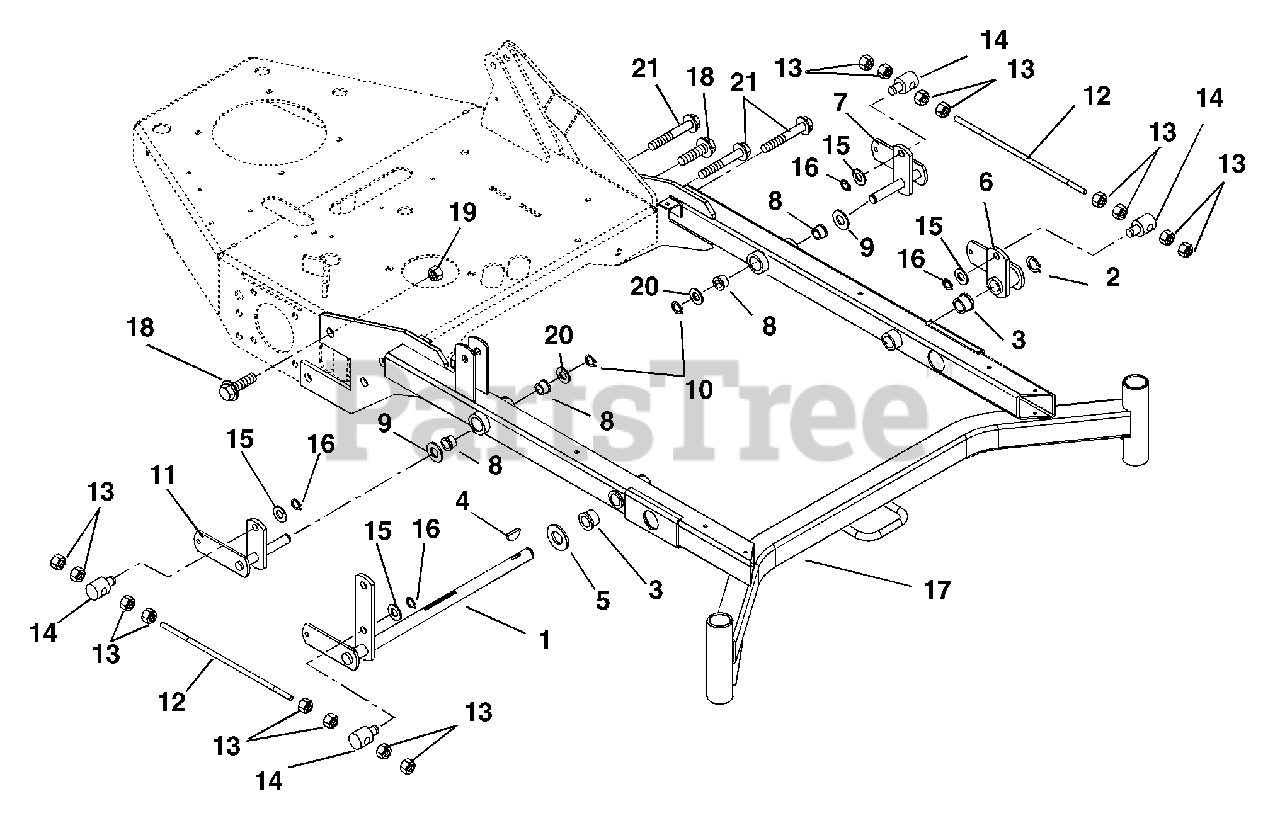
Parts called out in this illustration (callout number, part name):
1	Lift-Mower
2	Ring-Retaining-External 1.00 x .078
3	Bushing-Flange-Nylon 1.02 x 1.39 x .75 x 1.75
4	Key-Woodruff .25 x 1.00
5	Washer-Flat-Steel 1.063 x 2.00 x .134
6	Weldment, Lift Arm-Front
7	Weldment, Lift Arm-Shaft-Left Hand
8	Bushing-Flange-Nylon .762 x 1.0 x .580 x 1.48
9	Washer-Hardened-Steel .758 x 1.23 x .031
10	Ring-Retaining-External .689 x .077
11	Weldment, Lift Arm Shaft-Right Hand
12	Rod-Lift Assist
13	Nut-Jam .50-13
14	Pivot-Mower Lift
15	Washer-Flat-Steel .630 x 1.005 x .062
16	Ring-Retaining-External .625 x 050
17	Weldment, Mower Frame 50/60
17	Weldment, Mower Frame 72
18	Bolt-Hex .62-11 x 1.50 Grade 5
19	Nut-Locking-Nylon .625-11
20	Washer-Flat-Steel .812 x 1.50 x .135
21	Bolt-Hex .62-11x1.75 Grade 5
